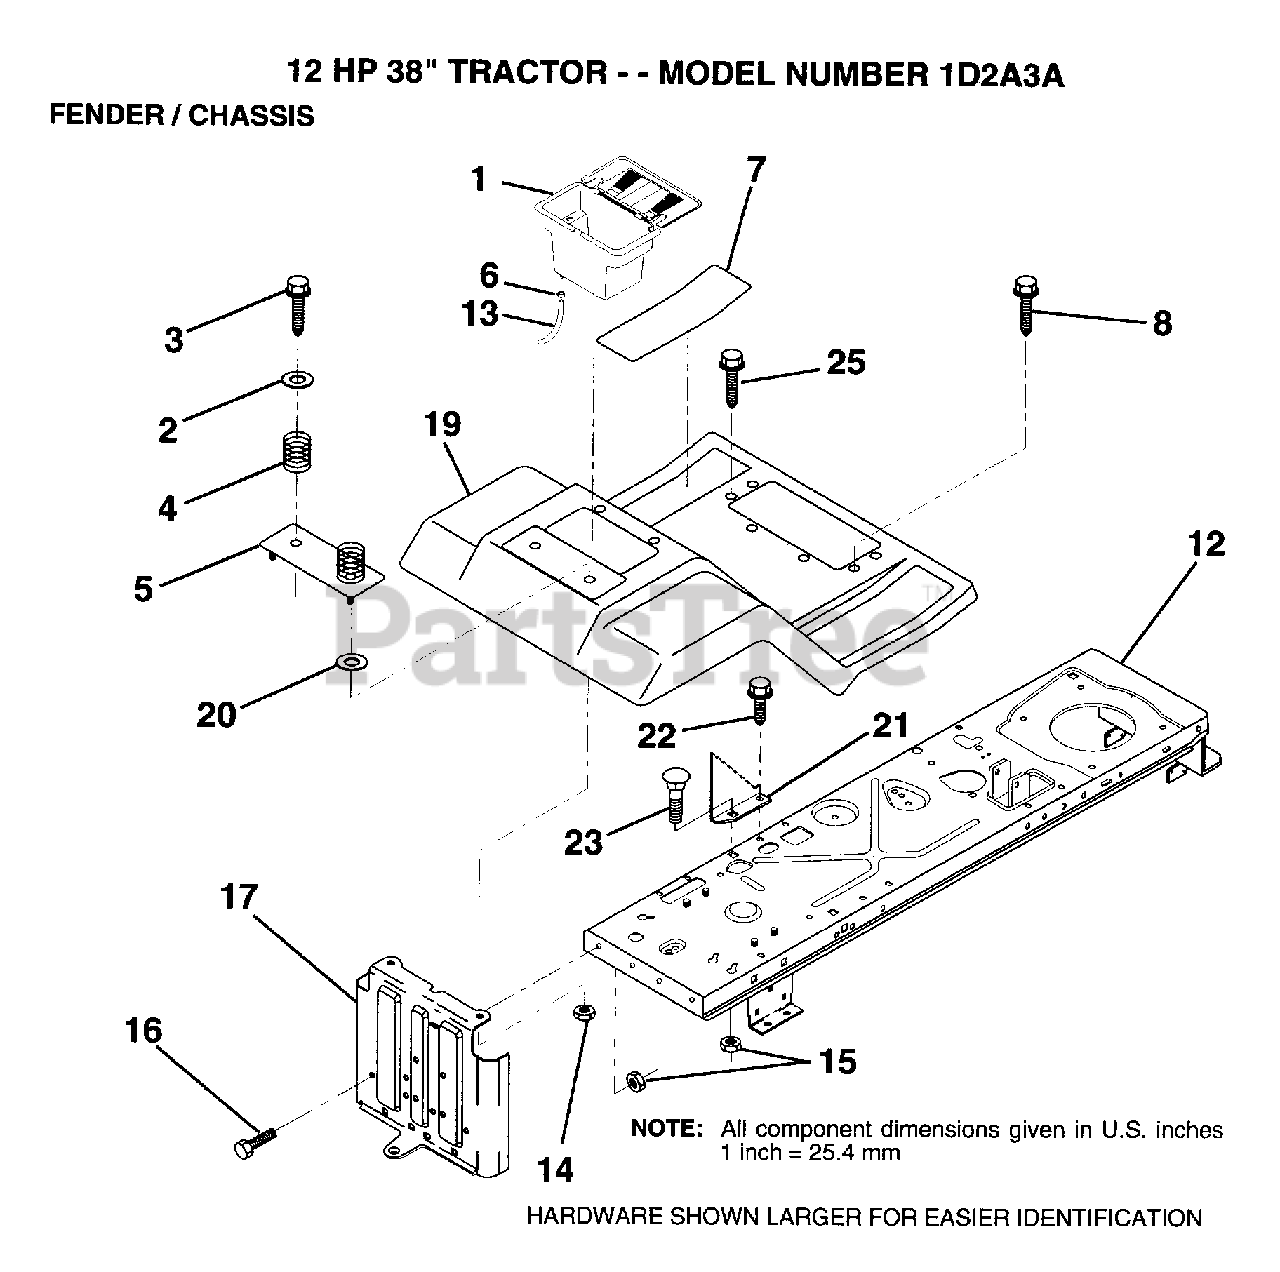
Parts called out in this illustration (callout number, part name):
2	WASHER
3	SCREW
4	SPRING COMPRESSIO
5	BTRY FENDER PLATE
6	HOSE CLAMP T
7	PAD FOOTREST
8	SCREW
13	TUBE T
14	NUT
16	BOLT
17	DRAWBAR
22	SCREW LT
25	SCREW TI
